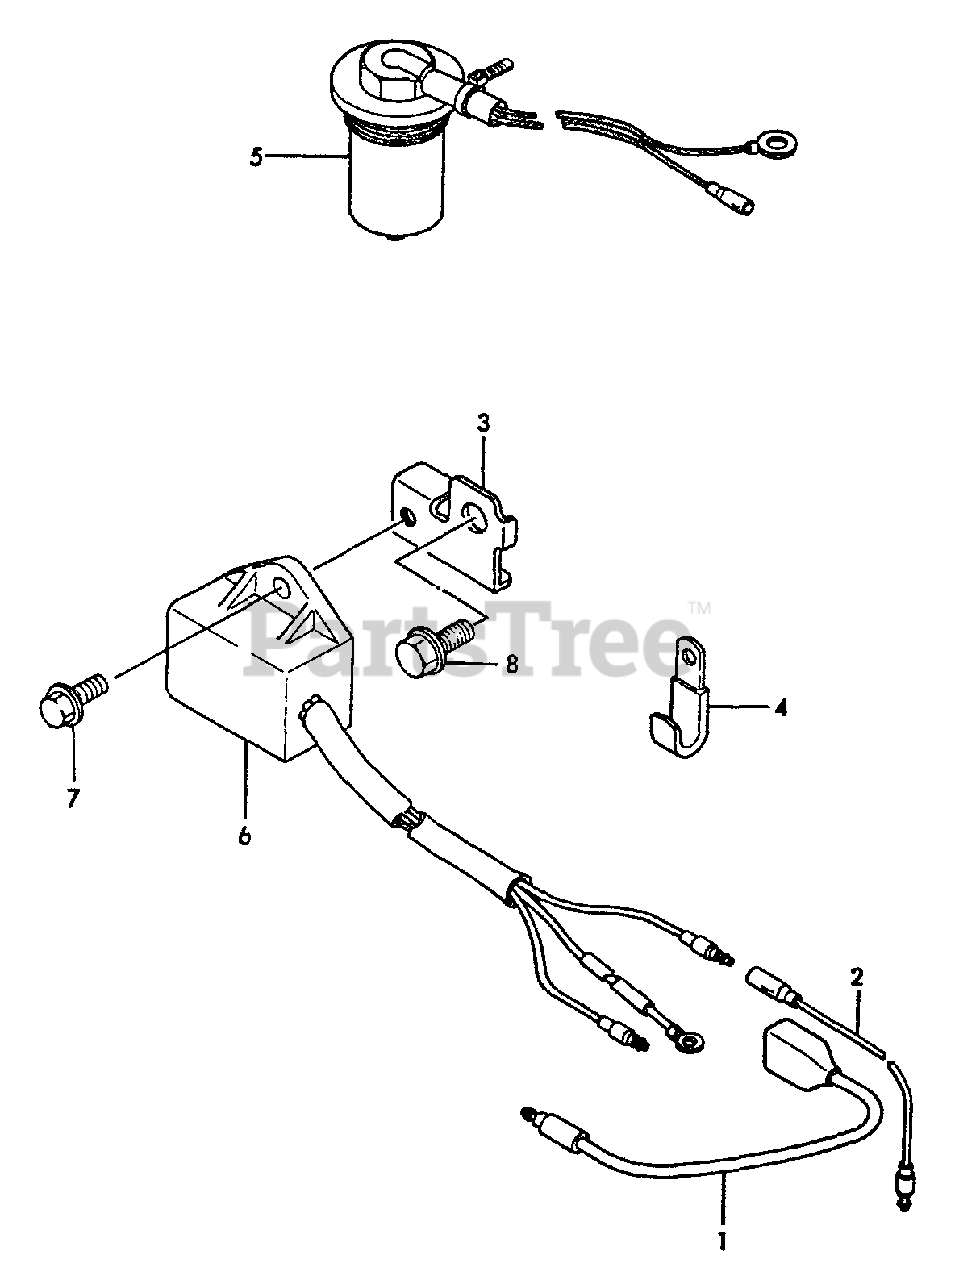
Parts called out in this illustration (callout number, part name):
1	WIRE
2	WIRE
3	STAY, SENSOR UNIT
4	CLAMP
5	SENSOR, OIL LEVEL
6	SENSOR, OIL
7	BOLT - 6X12 -- PLATED
8	BOLT - 8X14 -- PLATED
